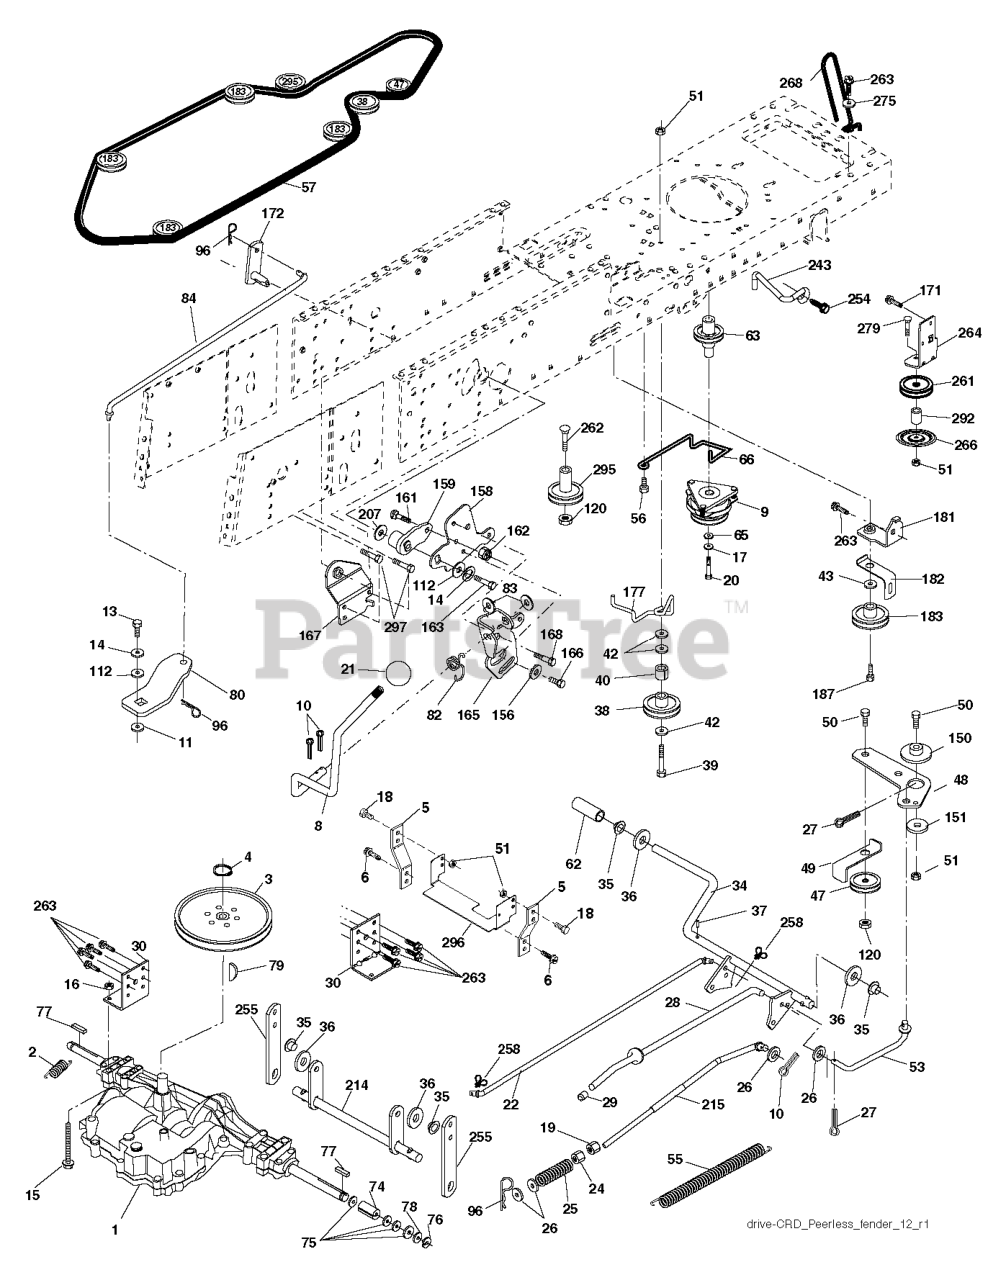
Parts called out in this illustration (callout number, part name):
1	TRANSAXLE (206-546) 6SP.CRD
2	SPRING,BRAKE RETURN
3	PULLEY
4	RETAINING RING LT
5	STRAP TORQUE
6	SCREW 5/16"
8	ROD SHIFT FENDER ADJUST LT
9	CLUTCH.ELECTRIC.OGURA.EURO.
10	PIN COTTER
11	WASH-SHFT PLT LT
13	BOLT 1/4-28X3/4
14	LOCKWASHER
15	BOLT HEX 5/16-18 GR 5
16	NUT.71038.31-18.HEX.NYLOCK
19	NUT
20	BOLT HEX 7/16-20X4-1/4"
21	KNOB.DUCKHEAD.1/2
22	ROD
24	NUT
25	SPRING ROD LT
26	WASHER
27	COTTER PIN
28	ROD, PARKING BRAKE
29	CAP
30	BRKT, MOUNT TRNSAXLE
34	SHAFT, FOOT PEDAL
35	BEARING.NYLON
37	DRIVE PIN
38	PULLEY.FLAT
42	WASHER
47	IDLER PULLEY
48	BELLCRANK, CLUTCH
49	RETAIN BELT
50	BOLT.3/8-16X1.50
53	LINK.CLUTCH.7.66.2005
55	SPRING, RETURN LT
56	SCREW.3/8-16
57	V-BELT.KEV.111"
62	PEDAL COVER T
63	PULLEY.ENGINE.CVX.LT
65	LOCKWASHER
66	KEEPER BELT ENGINE
74	SPACER AXLE
77	SQUARE KEY
79	KEY STD (1373) DANA
82	SHIFT SPRING
83	WASHER
96	RETAINER M
120	NUT LOCK FLG 3/8-16 UNC
150	BUSHING.BELLCRANK.GRD.DR
151	WASHER 12/32X2X10GA
156	WASHER.SRRTD.5/16
158	BRACKET
159	RB HUB.SHIFT
161	BOLT
162	NUT.CROWNLOCK.1/4
165	RP BRACKET
166	CAPSCREW.HXHD.FLG.5/16-18X.625
167	BRACKET.SUPT.SHIFT.CRD
168	BOLT.SHOULDER.5/16-18X
172	SHAFT
181	BRACKET
182	BELT GUIDE
183	PULLEY.V-IDLER.
187	BOLT.5/16-18X1.25
207	WASHER NYL
214	LEVER
243	BRACKET, ANTI-ROTATION
254	SCREW 3/8-16X1
255	SHAFT
258	CLIP RETAINER
261	FLAT IDLER PULLEY
263	SCREW, 3/8-16X3/4
264	BRACKET.IDLER
266	PROTECTOR
268	GUARD MUFFLER
275	WASHER
292	SPACER
295	PULLEY IDLER COMPOSITE
297	SCREW LT.3/8-46X5/8
